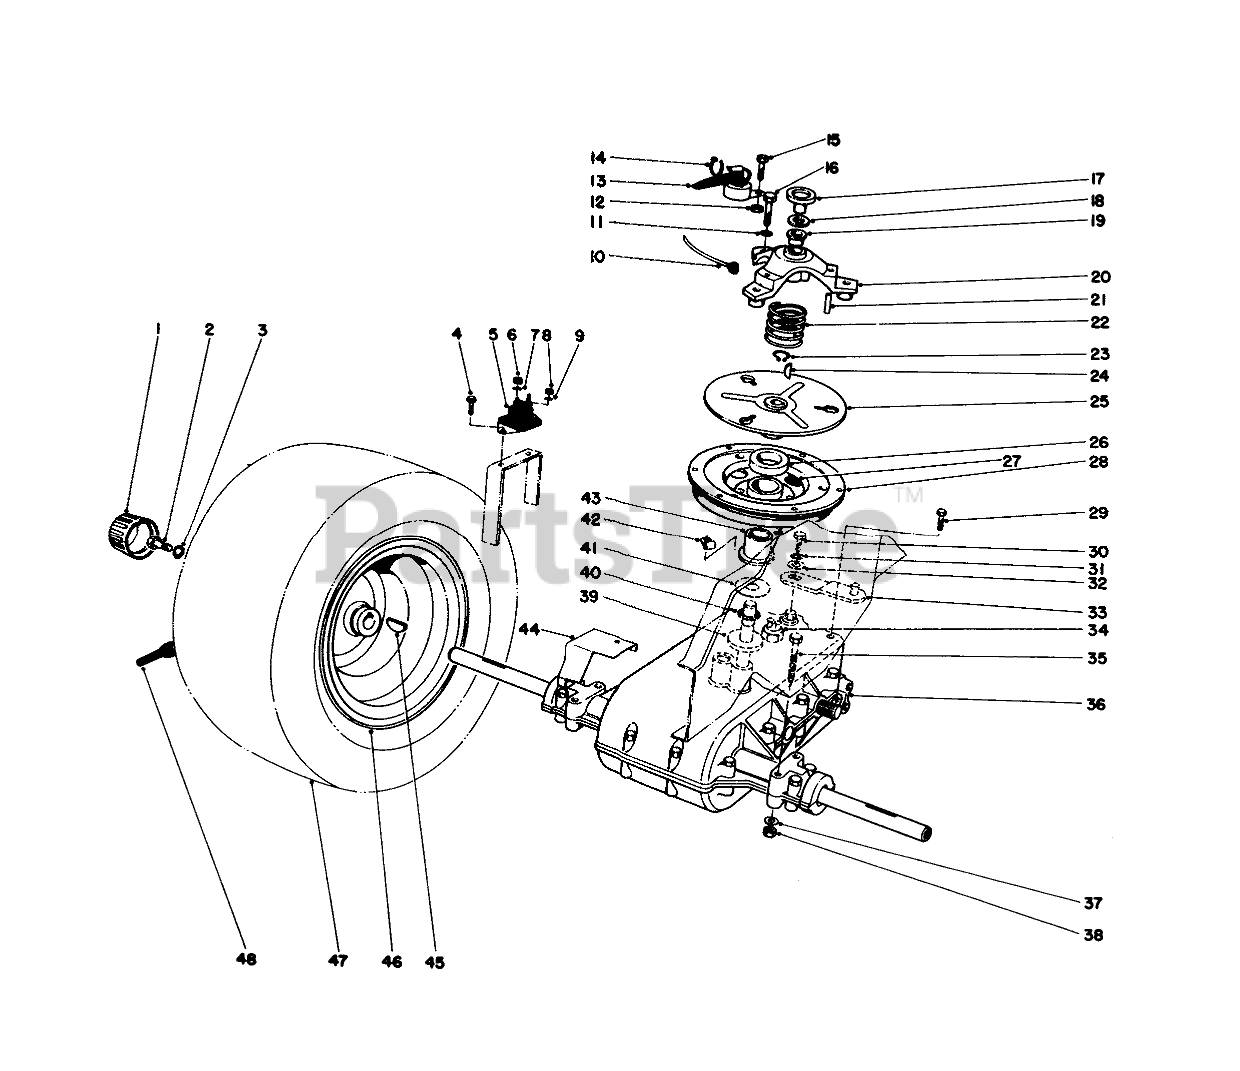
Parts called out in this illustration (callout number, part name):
1	Cap-Hub
2	SCREW-HH
3	WASHER-LOCK
4	SCREW-HWH
5	SOLENOID
6	NUT-JAM, BRASS
7	WASHER-LOCK
8	NUT-HEX
9	WASHER-LOCK
10	TIE-MOUNT, PUSH
11	WASHER-LOCK
12	NUT-LOCK, CONE
13	SEAT SWITCH
14	TIE-CABLE
15	SCREW-HH
16	SCREW-HH
17	Cap Clutch
18	THRUST RACE
19	BUSHING-FLANGE
20	Cover Assembly (Incl. Ref. #19 & 21)
21	NEEDLE BRG
22	Spring Compression
23	RING-SNAP, EXTERNAL
24	KEY-WOODRUFF
25	Clutch Plate
26	WASHER FELT
28	Sheave Assembly (Incl. Ref. #43)
29	SCREW-HWHTF
30	SCREW-HH
31	WASHER-LOCK
32	WASHER-FLAT
33	SHIFT LEVER WA B
34	NEUTRAL SWITCH
35	SCREW-HH
36	Transaxle
37	WASHER-PLAIN
38	NUT-LOCK, CONE
39	THRUST WASHER
40	NEEDLE BRG
41	THRUST WASHER
42	CLIP-FUEL LINE
43	Bushing
44	GRASS SHIELD B
45	WOODRUFF KEY
46	Rim
47	16 X 7.5-8 REAR TIRE
